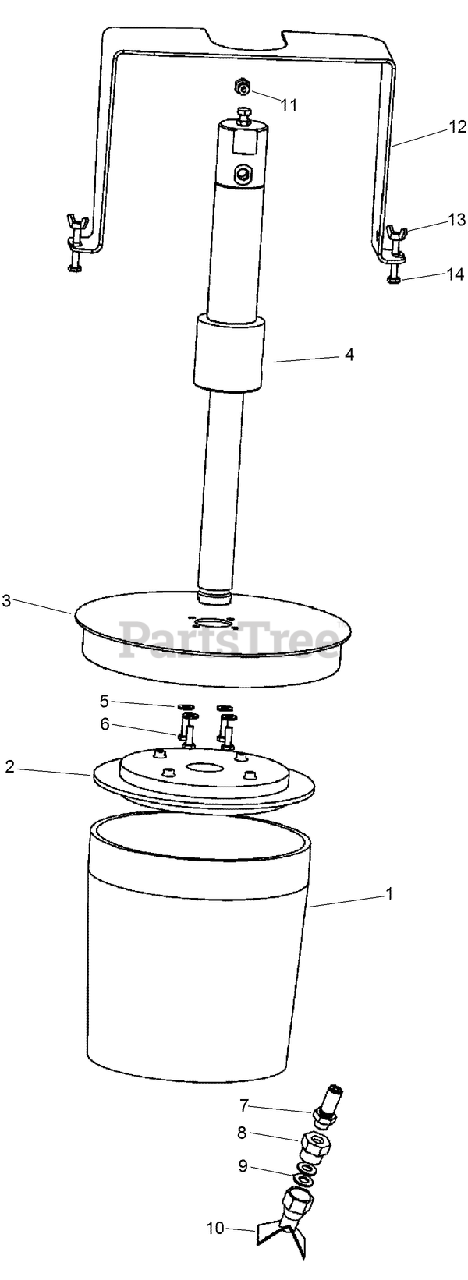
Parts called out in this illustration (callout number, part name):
1	COMPOUND-THREAD
2	SEAL - Rubber, Follower
3	WELDMENT - Cover
4	HYD GREASE PUMP ASM
5	WASHER-FLAT
7	CONNECTION - Bulkhead, Straight -4 ORFS / -4 ORB
8	REDUCER-STRAIGHT, THREADED
9	WASHER - 0.406 x 0.812 x 0.065 in HDN ZND
10	NOZZLE - Spray, Airless
11	PLUG - Hex, ORB 1/4
12	TIE DOWN - Grease Cover
13	NUT - Wing, 1/4 - 20 UNC ZND
14	BOLT - Hex Hd 0.25 x 1.75 GR8 ZND
